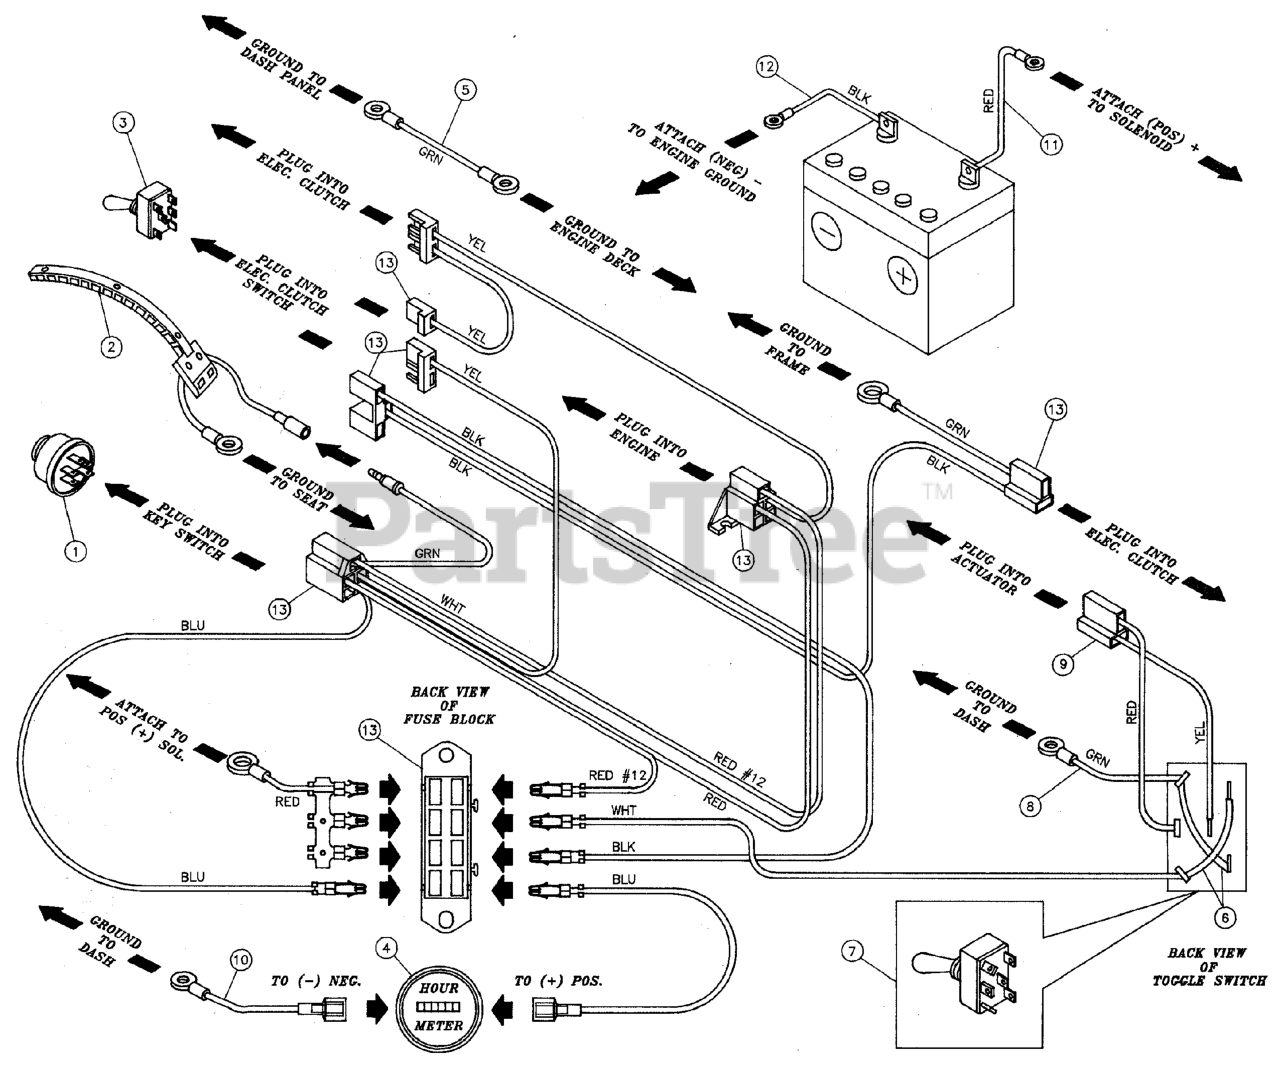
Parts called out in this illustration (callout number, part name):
1	SWITCH, Ignition
2	Seat Switch
3	SWITCH, Electric Clutch
4	HOUR METER
5	Extra Ground Wire
6	Jumper Wire
7	Actuator Switch
8	Switch Ground Wire
9	Actuator Wire Assembly
10	Hour Meter Ground Wire
11	POSITIVE (+) BATTERY CABLE, 30"
12	BATTERY CABLE, NEG, 22, 1/4-5/16
13	Rider Main Harness
